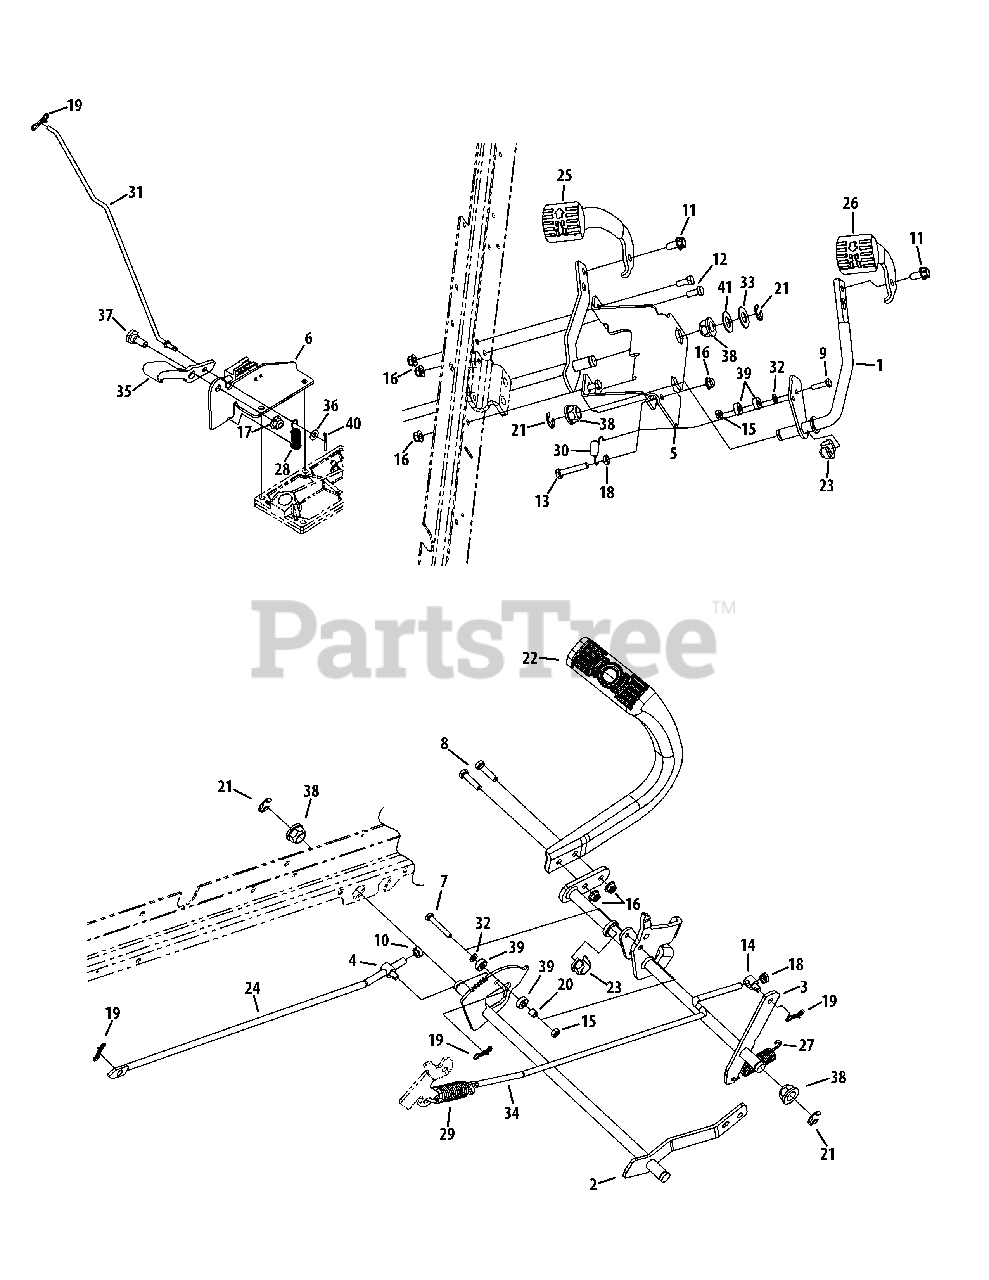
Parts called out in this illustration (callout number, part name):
1	Reverse Shaft Assembly
2	Forward Shaft Assembly
3	Brake Shaft Assembly
4	Ferrule, 3/8-16 x .312
5	Pedal Bracket
6	Cruise Pedal Mount Bracket
7	Hex Screw, 1/4-20 x 1.75
8	Hex Screw, 5/16-18 x 1.25
9	Hex Screw, 1/4-20 x 1.00
10	Jam Nut, 3/8-16
11	Hex Washer Screw, 3/8-16 x .750
12	Hex Screw, 5/16-18 x .75
13	Hex Screw, 5/16-18 x 1.75
14	Ferrule, 5/16-18 x .312
15	Hex Lock Nut, 1/4-20
16	Flange Lock Nut, 5/16-18
17	Flange Lock Nut, 3/8-16
18	Jam Nut, 5/16-18
19	Bow-Tie Cotter Pin, 72
20	Spacer, .375 x .25 x .335
21	E-Ring, .625
22	Pedal Bracket
23	Hex Flange Bearing, .628
24	Hydro Control Rod
25	Forward Pedal
26	Reverse Pedal
27	Extension Spring, .770 x 3.720
28	Cruise Extension Spring
29	Extension Spring, .95 x 4.00
30	Extension Spring, .51 x 2.12
31	Latch Control Rod
32	Flat Washer, .281 x .50 x .063
33	Flat Washer, .64 x 1.24 x .06
35	Cruise Latch
36	Flat Washer, .271 x .630 x .065
37	Shoulder Screw, 3/8-16 x .50 x .27
38	Hex Flange Bearing
39	Ball Bearing, .25 x .6875 x .25
40	Cotter Pin 3/32" Dia. x 1" Lg.
41	Washer, .625 x 1.00 x .030
